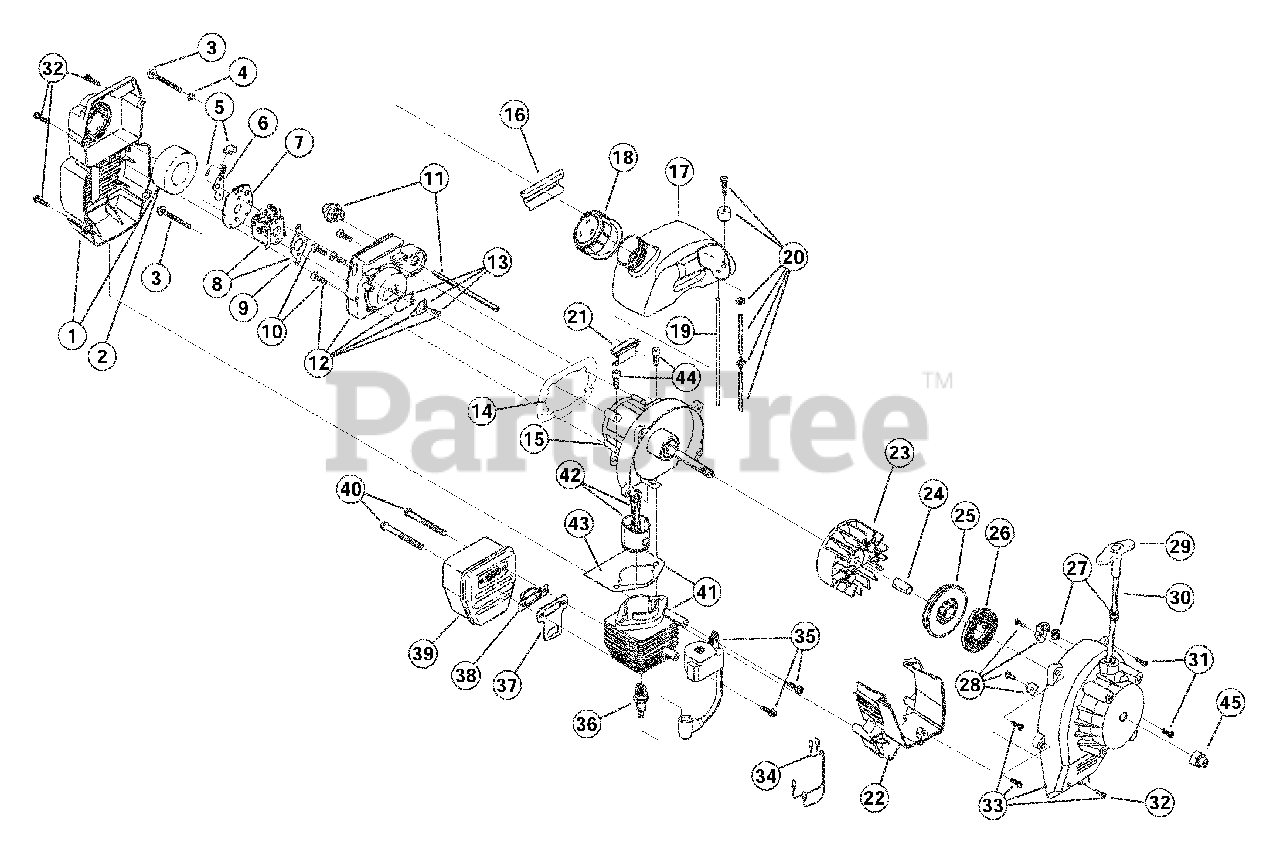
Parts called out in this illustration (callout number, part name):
1	Air Cleaner/Muffler Cover Assembly
2	Air Cleaner Filter
3	Carburetor Mounting Screw
4	Wave Washer
5	Choke Knob and Screw
6	Choke Lever Assembly
7	Choke Lever and Plate
8	Carburetor Assembly
9	Carburetor Gasket
10	Carb Mount Screw
11	Primer and Hose Assembly
12	Carb Mount Assembly
13	Reed Assembly
14	Carburetor Mount Gasket
15	Crank Case Service Assembly
16	Rear Mounting Pad
17	Fuel Tank Assembly
18	Fuel Cap Assembly
19	Fuel Return Line
20	Fuel Line Assembly
21	Front Mounting Pad
22	Shroud Extension
23	Flywheel Assembly
24	Spacer
25	Recoil Pulley Assembly
26	Recoil Spring
27	Rope Guide
28	Pulley Retainer Assembly
29	Pull Handle
31	Housing Screw
32	Cover Screw
33	Starter Housing Assembly
34	Wire Lead Assembly
35	Module Assembly
36	Spark Plug
37	Exhaust Gasket
38	Spark Arrestor Screen
39	Muffler Assembly
40	Muffler Mounting Bolt Assembly
41	Cylinder Assembly
42	Piston and Rod Assembly
43	Cylinder Gasket
44	Cylinder Bolt
45	Crankshaft Extension
